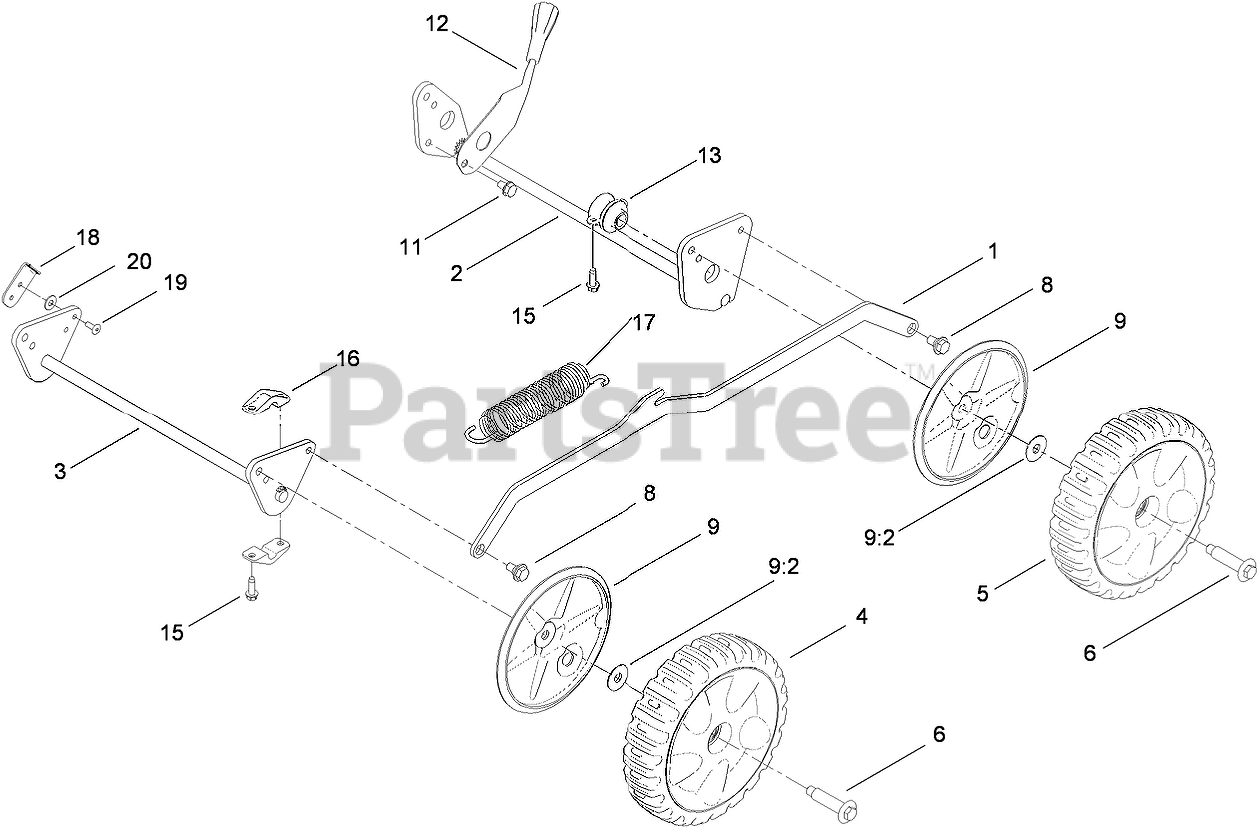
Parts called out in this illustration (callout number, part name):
1	BAR-CROSS, HOC
2	BAR-PIVOT, REAR
3	FRONT PIVOT BAR ASM
4	8 INCH WHEEL ASM
5	8 INCH WHEEL AND GEAR ASM
6	BOLT-SHOULDER
8	SCREW-SHOULDER
9	WHEEL COVER ASM
9:2	WASHER-STEPPED
11	SCREW-HHF
12	HANDLE-LIFT ASSIST
13	BUSHING ASM
15	SCREW-HWHTF
16	MOUNT-AXLE, FRONT
17	SPRING-EXTENSION
18	INDICATOR-HOC
19	RIVET-BLIND
20	WASHER-FLAT
